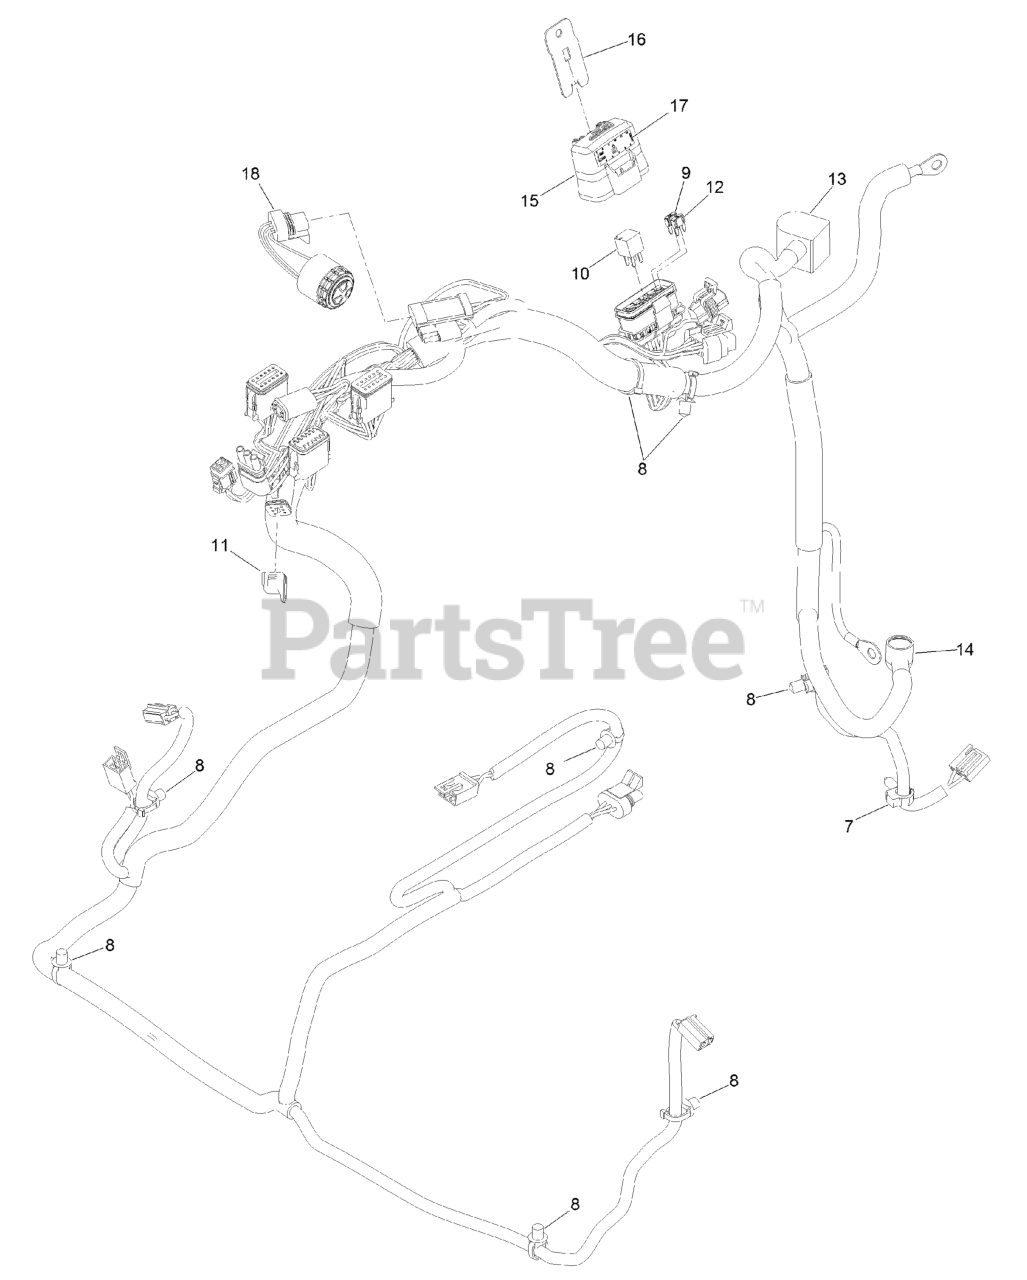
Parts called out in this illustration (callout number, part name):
7	CLIP-HARNESS
8	CLIP-TIE
9	FUSE-MINI BLADE, 20 AMP
10	RELAY-MICRO
11	CAP-PLUG, 6 WAY
12	FUSE-MINI BLADE, 15 AMP
13	INSULATOR-BATTERY
14	INSULATOR-SOLENOID
15	COVER-BLOCK, FUSE
16	CLIP-MOUNTING
17	DECAL-FUSE
18	ALARM-DUAL TONE
